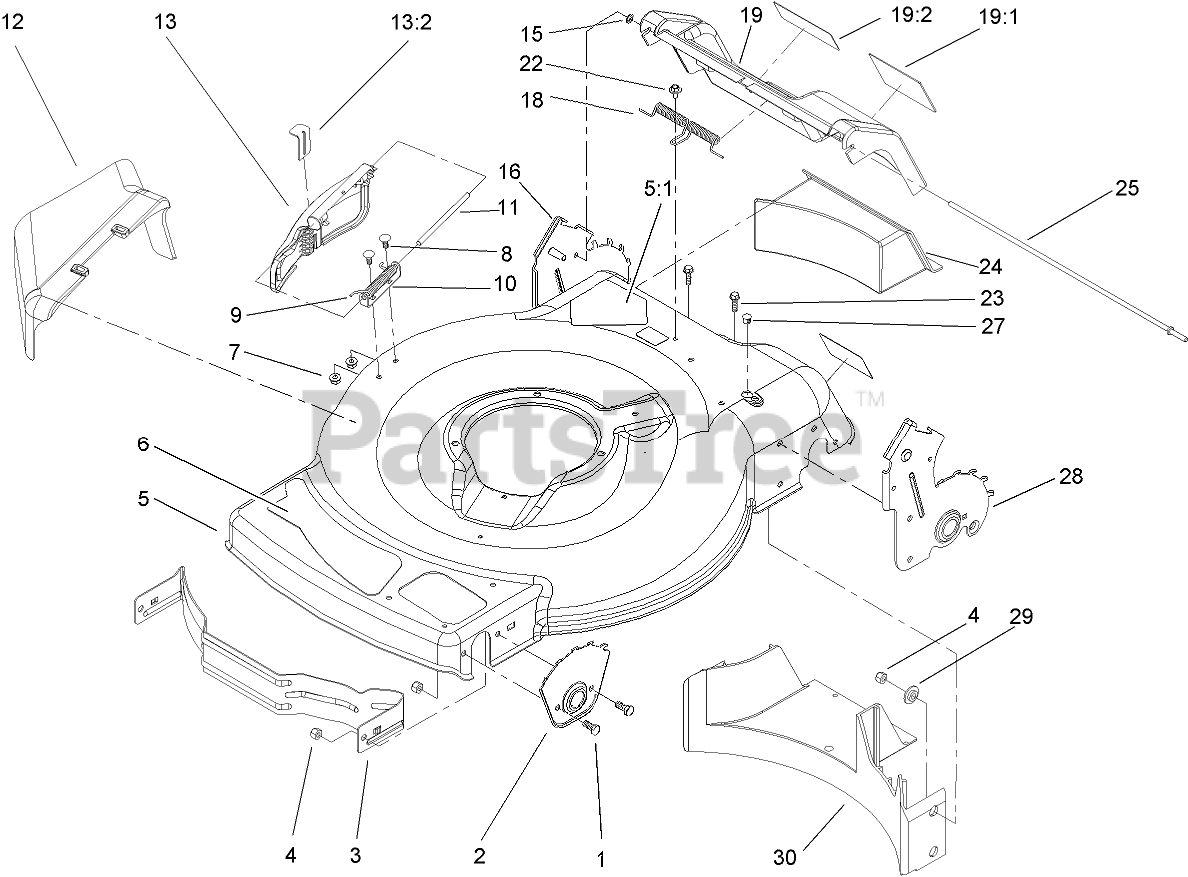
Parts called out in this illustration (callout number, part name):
1	SCREW-HH
2	Plate-HOC, Front
3	Baffle-Front
4	NUT-LOCK, NI
5	HOUSING (only on: 20013)
5	HOUSING (only on: 20017)
5:1	DECAL-DANGER, CUT FINGER (only on: 20013)
5:1	DECAL-DANGER (only on: 20017)
6	Decal-Deck
7	NUT-HHF
8	SCREW-CARR
9	SPRING-TORSION
10	BRACKET-COVER
11	ROD-COVER
12	CHUTE-DISCHARGE, SIDE
13	DOOR-DISCHARGE ASM
13:2	LEVER-LATCH
15	NUT-PUSH
16	RH REAR HOC PLATE ASM (only on: 20017)
16	RH REAR HOC PLATE ASM (only on: 20013)
18	Spring-Door, Rear
19	DOOR (only on: 20017)
19	DOOR (only on: 20013)
19:1	DECAL-WARNING (only on: 20013)
19:2	DECAL-WARNING (only on: 20013)
19:2	DECAL-WARNING (only on: 20017)
22	SCREW AND WASHER ASM
23	SCREW-HWH
24	Plug-Discharge, Rear
25	Rod-Pivot, Rear Door
27	Plug-Dome
28	LH REAR HOC PLATE ASM (only on: 20017)
28	LH REAR HOC PLATE ASM (only on: 20013)
29	Washer-Stepped
30	Baffle-Rear
